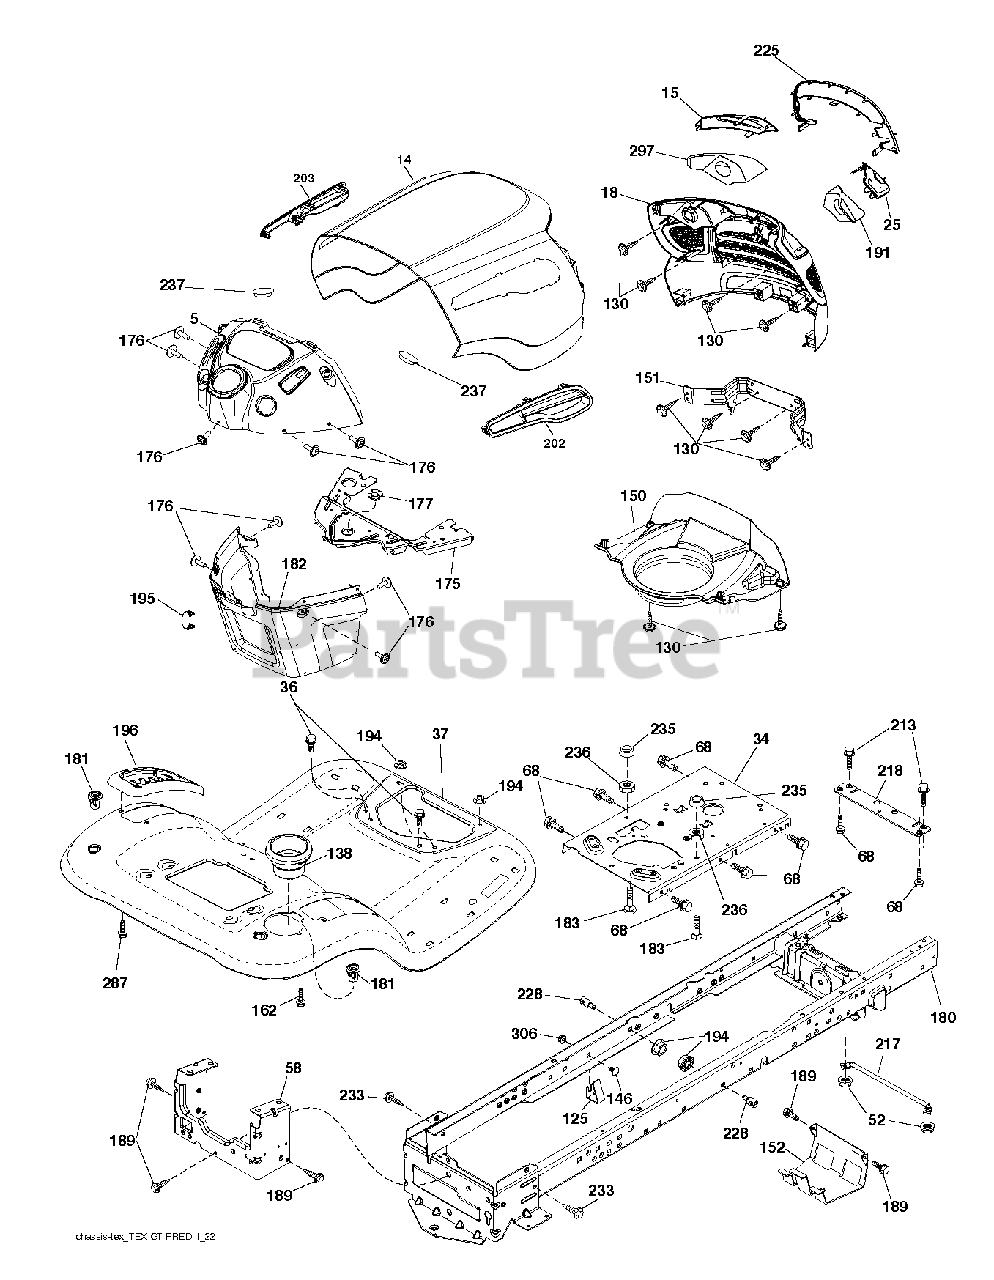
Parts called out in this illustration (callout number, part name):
14	HOOD.PNT.PREDATOR.YT/GT.BLACK
15	LENS.MCCULLOCH.GT.LH
18	GRILLE.PREDGT2.GEN
25	Lens, RH Mcculloch GT
34	PLATE.ENGINE.WELDED.CHASSIS
36	SCREW 5/16"
37	FENDER.TLT.W/CPH.428
52	LOCKNUT
58	DRAWBAR UPPER 2PC SMALL FENDER
68	SCREW LT
125	CLIP.FUEL.LINE
130	SCREW.#10 X 0.750.BOS (2 2)
138	CUPHOLDER.TL.TEX.BLACK
146	BOLT.RDHD.SHT.SQNK.3/8-16X5/8
150	PREDATOR.YT.GT.HOOD.AIR DUCT
151	BRACKET.PIVOT.PREDATOR
152	SHIELD.BROWNING.W/TEX
162	SCREW.HI-LO.CONSOLE
175	PLATE.CROSSMEMBER.HUSQ
176	SCREW.#10-24X5/8.RN.QU
177	BUSHING STEERING
180	CHASS.WLDMNT.TL.12GA/2P.48/54
181	FEND/FTRST.PCH.CPH.NFW
182	DASH LOWER.HUSQ.PRED NO CRUISE
183	BOLT.5/16-18X1-1/4 FULL THD
189	SCREW
191	REFLECTOR.MCCULLOCH.GT.RH
194	NUT LOCK HEX FLANGE 5/16-18
195	PLUG.HOLE.DASH.
202	VENT.SIDE.HOOD.RH.PREDATOR.BLK
203	VENT.SIDE.HOOD.LH.PREDATOR.BLK
213	BOLT
217	ROD.PIVOT.HOOD
218	X-PIECE.HOOD.STOP.NON/
228	STUD.FASTNER.W/ANTI-ROTATE
233	BOLT.SHOULDER
235	SPACER FENDER
236	NUT.CENTERLOCK.5/16-
237	PLUG.MOUNT.CARGO.BLK
287	SCREW 1/4X20
297	REFLECTOR.MCCULLOCH.GT.LH
306	NUT LOCK FLG 3/8-16 UNC
